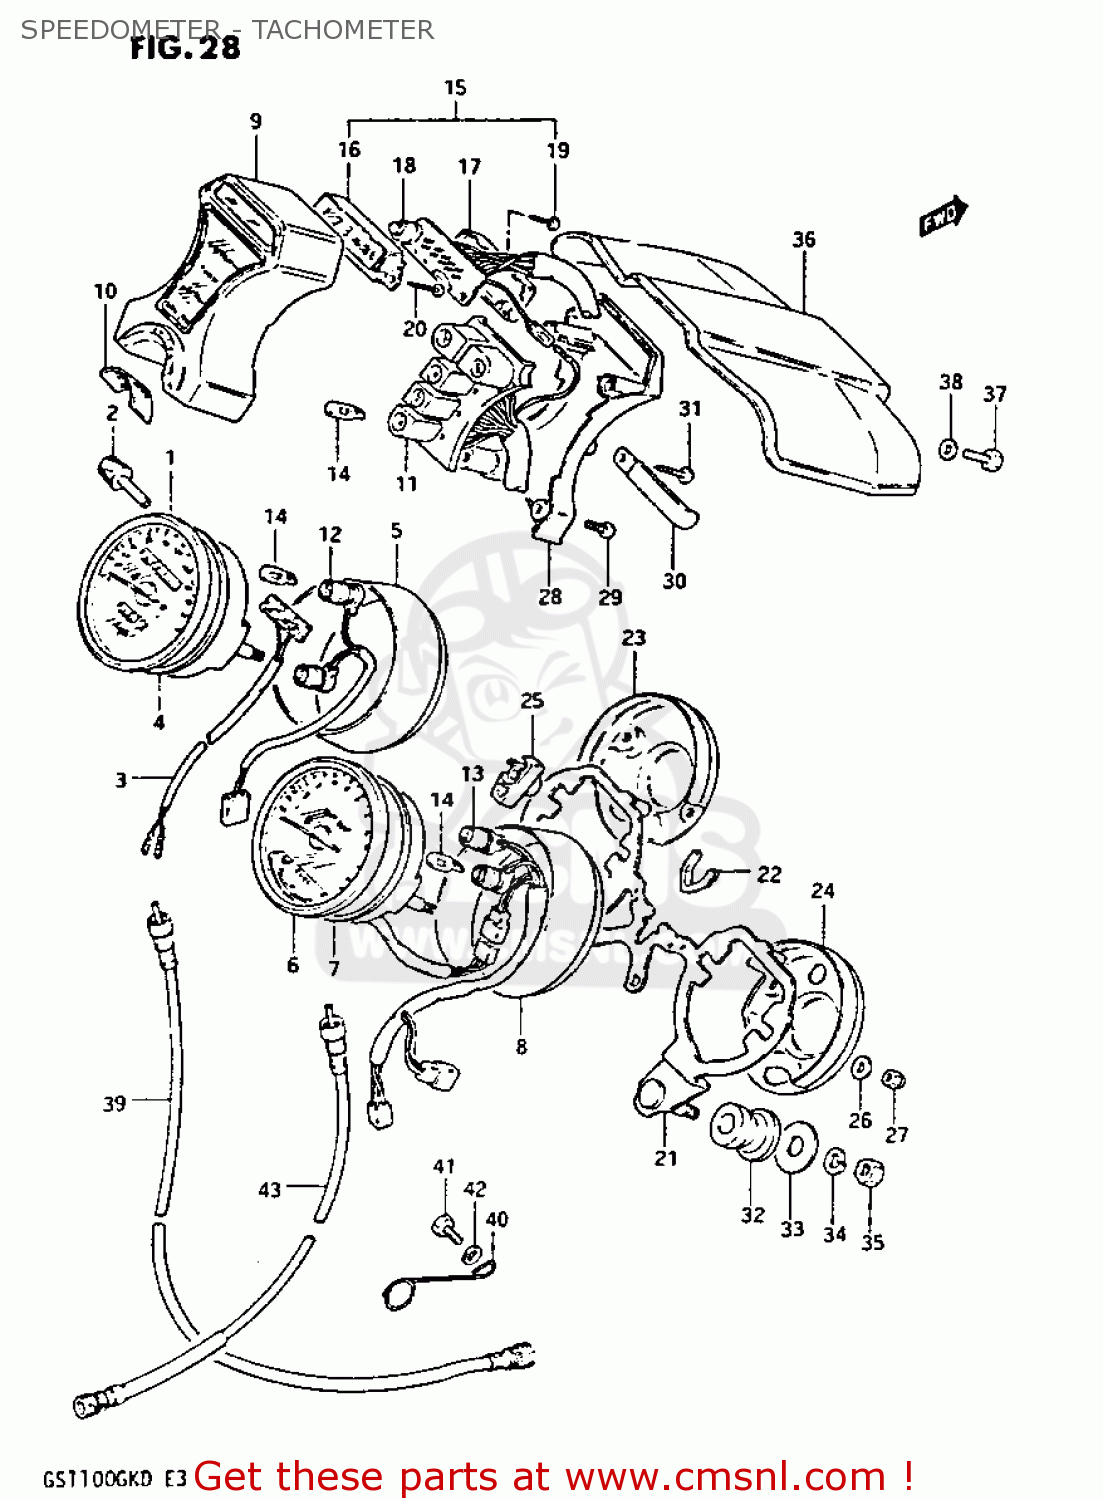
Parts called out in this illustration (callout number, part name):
1	METER,SPEEDOMETER (KM/MPH)
2	KNOB,TRIP
3	WIRE,LEAD SWITCH
4	CUSHION,METER
5	COVER,SPEEDOMETER
6	METER,TACHOMETER
7	CUSHION,METER
8	COVER,TACHOMETER
9	CASE,PILOT BOX
10	SEAL,IGNITION SWITCH
11	SOCKET
12	SOCKET,SPEEDOMETER
13	SOCKET,TACHOMETER
14	BULB(12V3.4W,T10)
15	INDICATOR ASSEMBLY,GEAR POSITION
16	CASE,GEAR INDICATOR
17	COVER,LWR
18	BULB(14V1.12W)
19	SCREW,GEAR INDICATOR
20	SCREW
21	BRACKET,METER
22	BRACKET,COVER
23	COVER,METER,UNDER
24	COVER,TACHOMETER,UNDER
25	CUSHION
26	WASHER
27	NUT
28	COVER,PILOT BOX
29	SCREW,PILOT BULB CASE
30	CLAMP,CORD
31	CROSS SCREW (4X8)
32	CUSHION,METER BRACKET
33	WASHER (8.5X20X1.6)
34	WASHER,LOCK,8.
35	NUT
36	HOOD,METER
37	BOLT
38	WASHER
39	CABLE ASSEMBLY,SPEEDOMETER
40	CLAMP,SPEEDOMETER CABLE
41	BOLT
42	WASHER
43	CABLE ASSEMBLY,TACHOMETER
